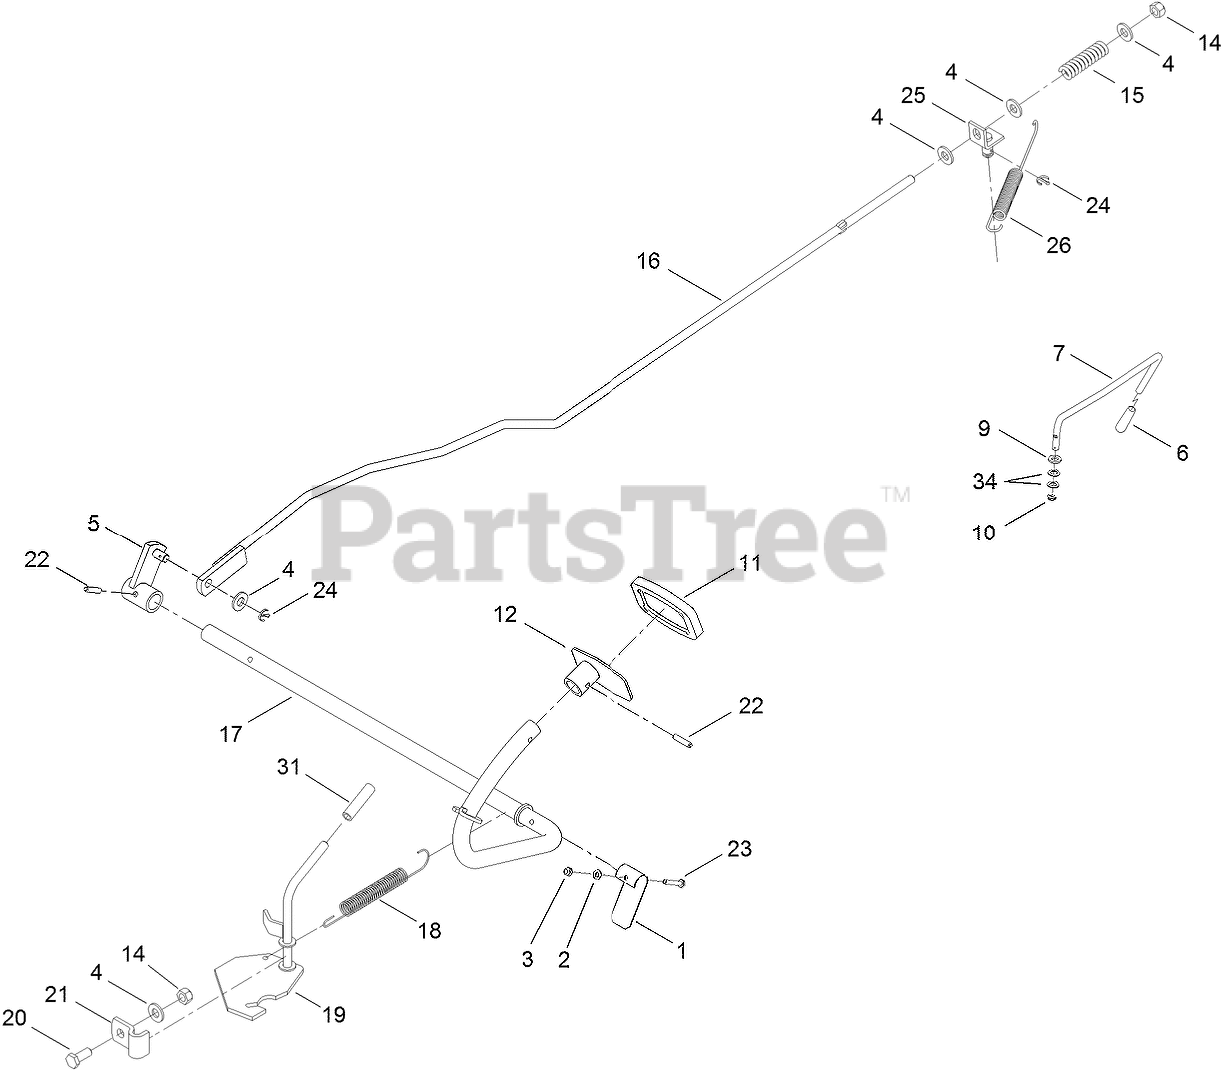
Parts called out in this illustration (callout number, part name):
1	LEVER-SPRING
2	WASHER
3	NUT-HEX
4	WASHER-PLAIN
5	BRACKET-ROD, BRAKE
6	CAP-BYPASS LEVER, HYDRO
7	ROD-LEVER, BYPASS
9	WASHER
10	PIN-COTTER
11	PAD-PEDAL
14	NUT-LOCK, NI
15	SPRING-BRAKE
16	ROD-CONNECTING, BRAKE
17	SHAFT-BRAKE
18	SPRING-BRAKE, HAND
19	LEVER-BRAKE, HAND
20	SCREW-HH
21	CLAMP-LEVER, PARKING BRAKE
22	PIN-SPRING
23	SCREW-HEX
24	PIN-COTTER
25	BRACKET-ROD, BRAKE
26	SPRING
34	Washer
